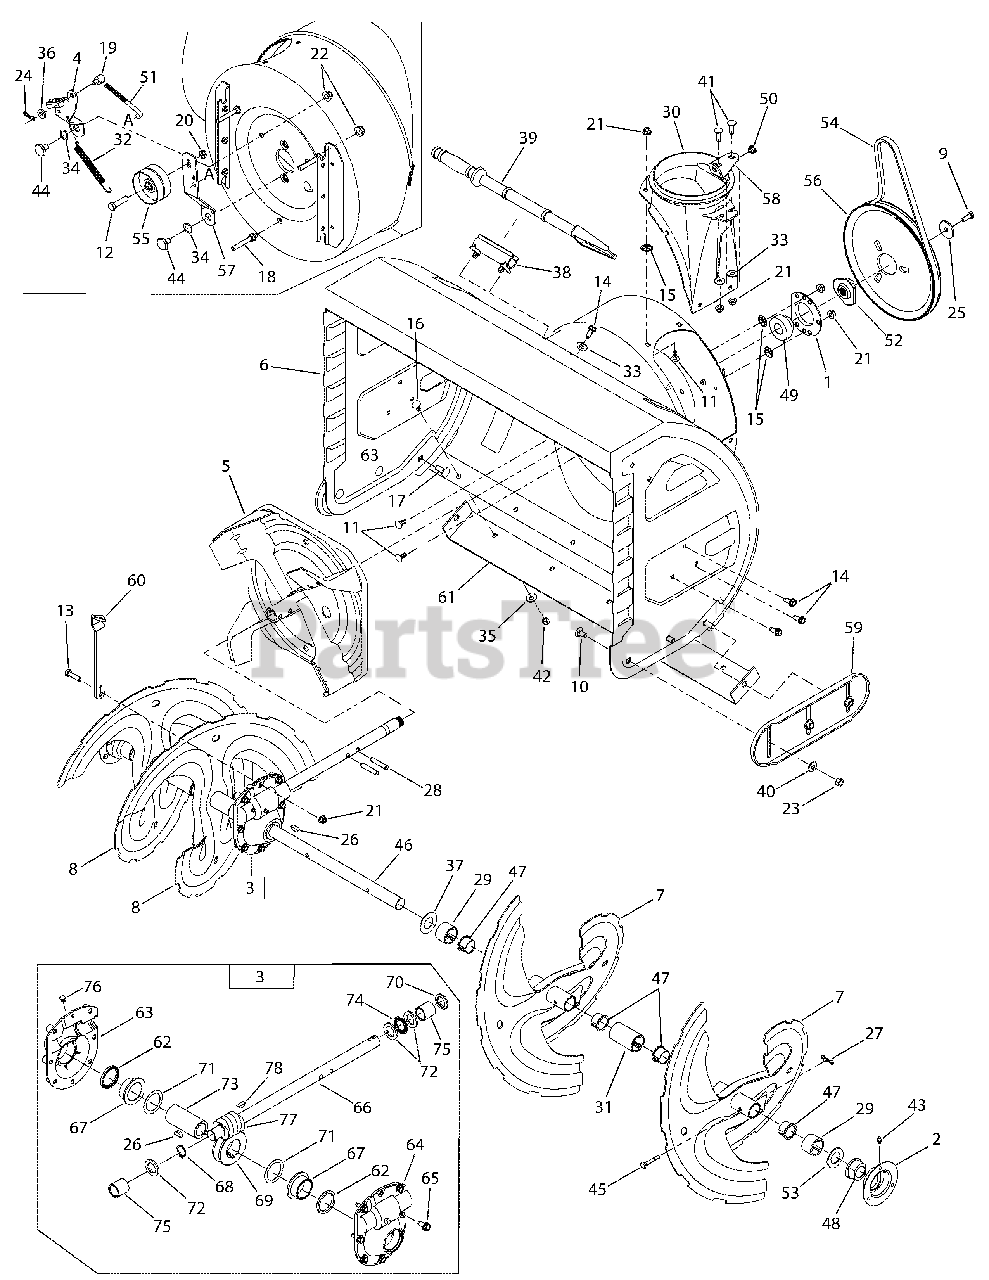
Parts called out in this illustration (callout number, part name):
1	Housing, Bearing
3	Gear Box Assembly
4	Bracket Ass’y, Auger Brake
9	Screw, Hex Cap Lock, 5/16-24 x .875 Gr8
10	Screw, Carriage, 3/8-16 x .75 Stainless
11	Screw, Carr, 5/16-18 x .75
12	Screw, Hex Cap, 3/8-24 x 1.5
13	Screw, Hex Cap, 5/16-18 x 1.0 Gr5
14	Screw, 5/16-18 x .750
16	Screw, Carriage, 5/16-18 x .75 Stainless
17	Screw, Carr,3/8-16 x 1.0 Stainless
18	Screw w/Stud, 5/16-18 x .4300
19	Ferrule
20	Nut, Hex Lock, 3/8-24
21	Nut, Hex Flange Lock, 5/16-18
22	Nut, Hex Flange Lock, 3/8-16
23	Nut, Hex Lock, 3/8-16 Stainless
24	Pin, Internal Cotter
25	Washer, Flat, .34 x 1.5 x .15 HT
26	Key, Woodruff, 1/4 x 3/4
27	Pin, Bowtie Cotter
28	Pin, Spirol, 5/16 x 1.75
29	Spacer, 1.0 x 1.5 x 1.0Lg
30	Adapter, Chute, 6"
31	Spacer, 1.0 x 1.5 x 1.0Lg - 30" ONLY
31	Spacer, 1.0 x 1.5 x 2.5Lg - 33" ONLY
32	Spring, Extension
33	Washer, Flat, .349 x .879 .063
34	Washer, Wave, .625 x .885 x .015
35	Washer, Bell., .34 x .872 x .06 Stainless
36	Washer, .344 x .75 x .12
37	Washer, 1.01 x 1.86 x .06
38	Clip, Mounting
39	Tool, Cleanout
40	Washer, Bell., .375 x .87 x .063 Stainless
41	Screw, Carriage, 5/16-18 x 1.0
42	Nut, Hex, 5/16-18 Stainless
43	Fitting, Lube
44	Screw, Shoulder, .625 x .17
45	Pin, Shear, .25 x 1.75
46	Shaft, Spiral, - 30" ONLY
46	Shaft, Spiral, - 33" ONLY
47	Bushing, Flange,
48	Bearing, Flange w/Flats
49	Bearing, Self Aligning
50	Bushing, Plastic, .38 ID
51	Rod, Auger Idler
52	Adapter, Pulley w/Pins
53	Spacer, 1.004 x 1.375 x .25
54	Belt, V, 1/2 x 42 - 30" ONLY
54	Belt, V, 1/2 x 44 - 33" ONLY
55	Pulley, Flat Idler, 2.75 OD
56	Pulley, Auger Drive, 10.0
57	Bracket, Auger Idler
61	Plate, Shave, Stainless - 30" ONLY
61	Plate, Shave, Stainless - 33" ONLY
62	Oil Seal
63	Hsg, Ass’y, Auger, RH (Incl. Ref. # 62 & 67)
64	Hsg, Ass’y, Auger, LH (Incl. Ref. # 62 & 67)
65	Scr, LD, 5/16-18 x .750
66	Shf, Drive, Auger
67	Flange Bearing
68	External, Retaining, Ring
69	Gear, Worm, LH
70	Seal, Oil
71	Wash, Flat, 1.52ID x 2.0 OD
72	Wash, Flat, .88 ID x .38 OD
73	Shf, Gear, Worm
74	Bearing, Thrust
75	Sleeve
77	Gear, Worm
78	Key, Hi Pro, 3/16 x 3/4
